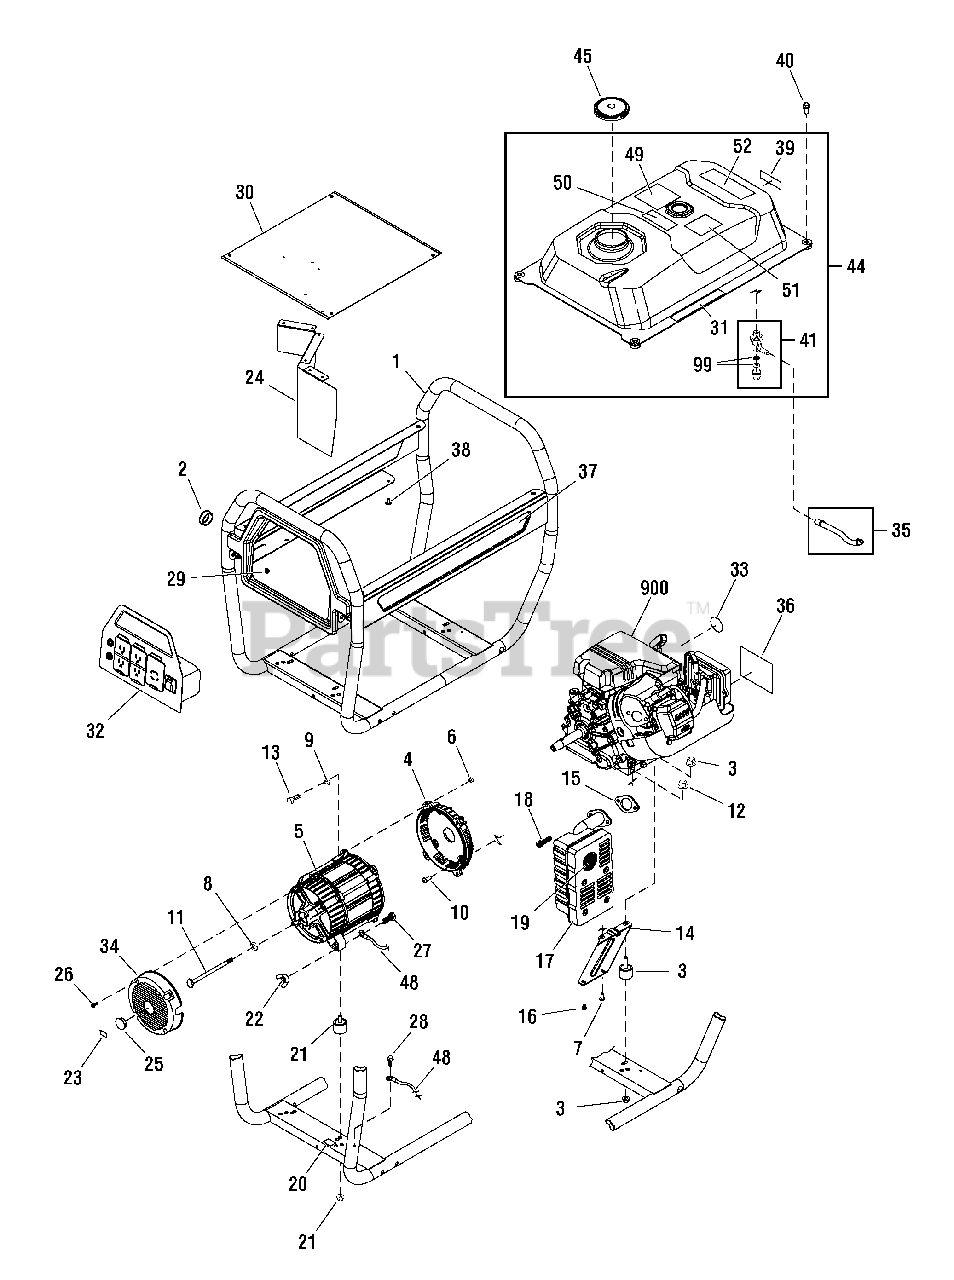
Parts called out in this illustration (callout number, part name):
1	CRADLE
3	MOUNT, Vibration
4	ADAPTER, Engine
5	ALTERNATOR
6	* NUT, Hex, M8 - 1.25
9	* WASHER, Lock, 5/16 - M8
10	* CAPSCREW, Trilobular, 3/8-16 x 7/8 Lg.
11	CAPSCREW, Hex Head, 5/16-24 x 7.44
13	* CAPSCREW, Hex Head, M8 - 1.25 x 25
16	* CAPSCREW, Hex Head, M6 - 1.0 x 12 w/LW
18	* CAPSCREW, Socket Head, M8 1.25 x 20
21	MOUNT, Vibration
27	* CAPSCREW, Hex Head, M6 - 1.0 x 40
29	* NUT, Palnut, M4
34	COVER, Rear Bearing
35	KIT, Fuel Hose
41	KIT, Fuel Valve
99	KIT, Fuel Valve Repair
900	** ENGINE
